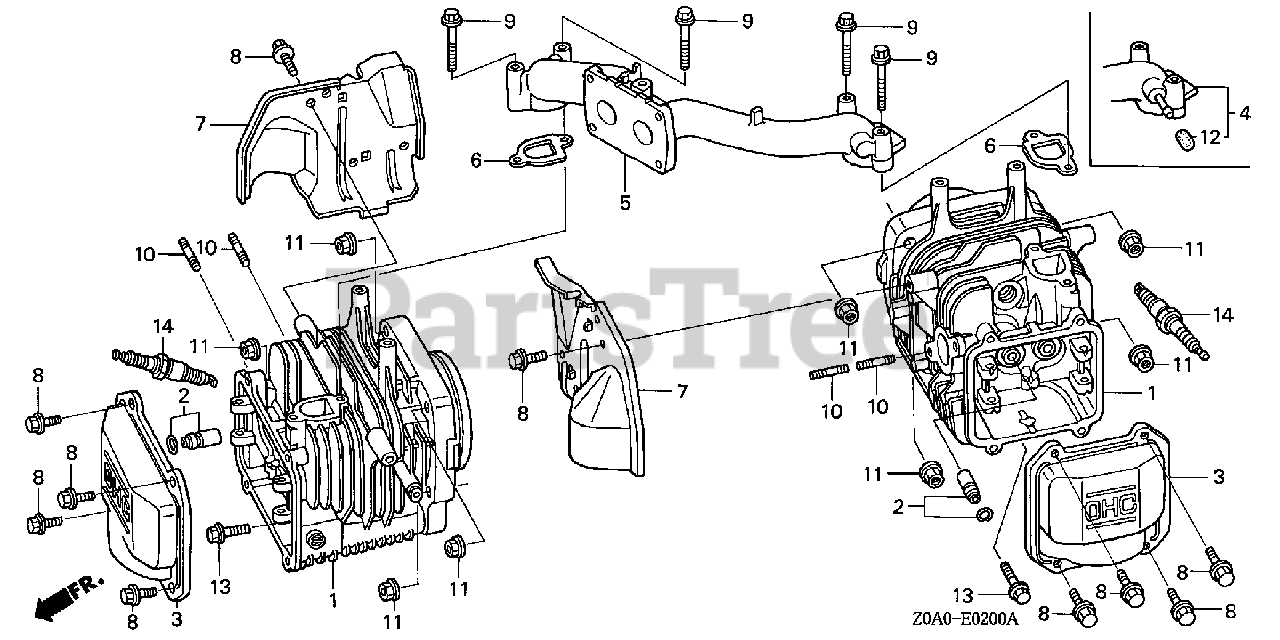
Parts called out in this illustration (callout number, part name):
1	CYLINDER
2	SEAL, VALVE STEM
3	COVER, HEAD
5	MANIFOLD, IN.
6	GASKET, IN. MANIFOLD
7	SHROUD
8	BOLT, FLANGE (6X12) (CT200)
9	BOLT, FLANGE (6X45)
10	BOLT, STUD (6X28)
11	NUT, FLANGE (8MM)
13	BOLT, FLANGE (6X30)
14	SPARK PLUG (BPR4ES) (NGK)
14	SPARK PLUG (W14EPR-U) (DENSO)
14	SPARK PLUG (BPR5ES) (NGK)
14	SPARK PLUG (W16EPR-U) (DENSO)
